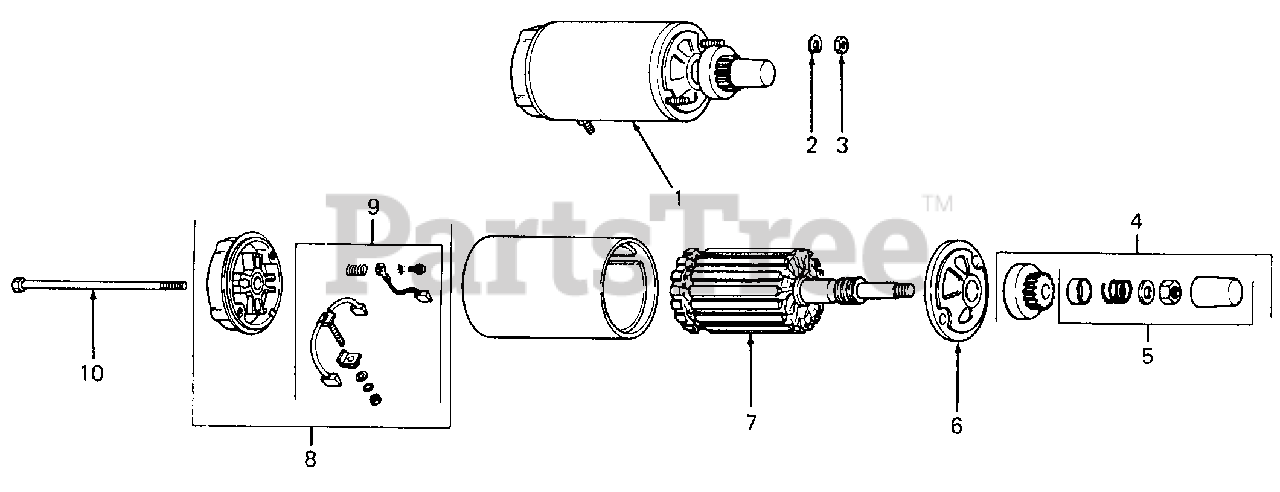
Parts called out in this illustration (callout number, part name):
1	Starter Assy
2	Washer, Lock
3	Nut, Hex, 1/4-20
4	Drive Kit
5	Drive Parts Kit
6	Cap, Drive End
8	Cap, Commutator End
9	Brush Kit
10	Bolt, Thru, 1/4-20 X 5-7/8
